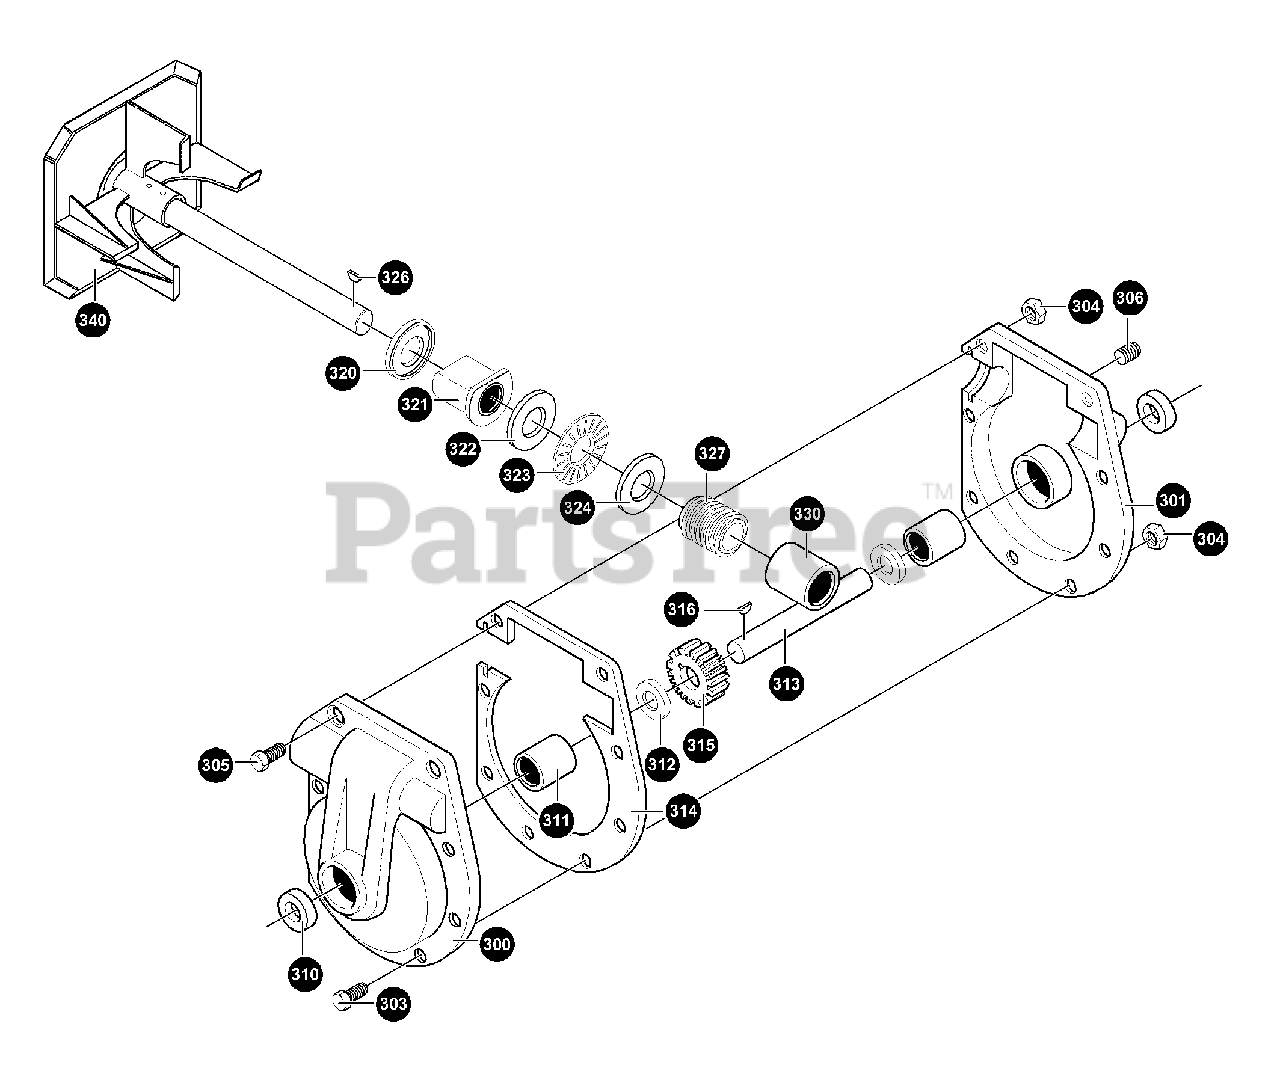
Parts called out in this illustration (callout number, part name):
300	CASE, GEAR RH
301	CASE, GEAR LH
303	SCREW, 5/16-24X1.00
304	NUT, 5/16-24
305	SCREW, 5/16-24X1.50
310	SEAL, OIL
311	BEARING, SLEEVE
312	WASHER, FLAT
313	SHAFT, AUGER
314	GASKET, GEAR BOX
320	RING, QUAD
321	BEARING, FLANGE
322	FLATWASHER .752X1.24X.093
323	BRNG, ROLL
324	FLATWASHER .752X1.24X.093
326	KEY, HI-PRO
330	BRNG, SLEV
340	IMPELLER, ASSY
